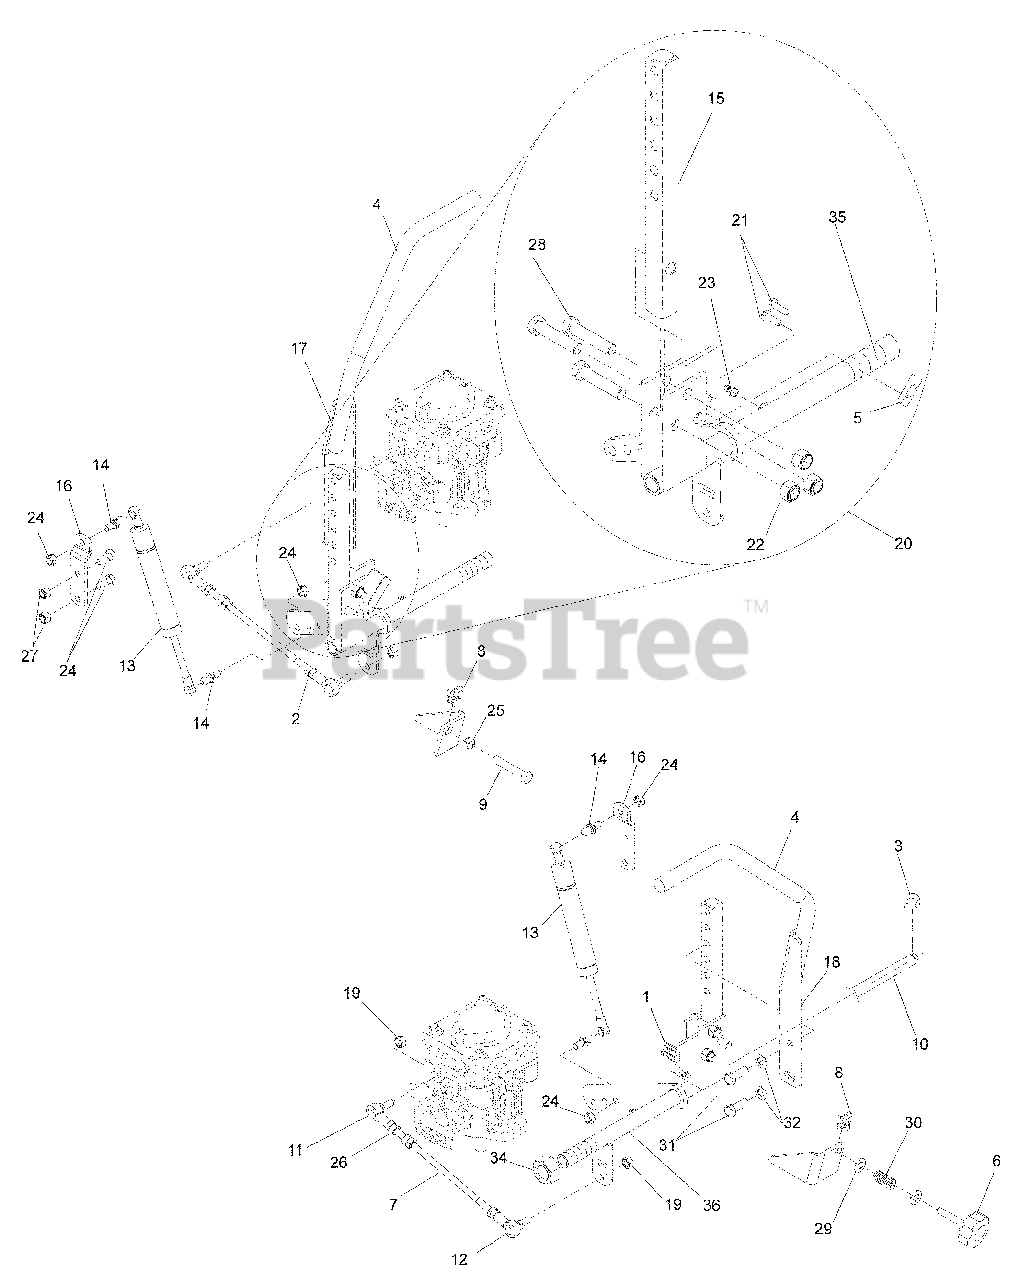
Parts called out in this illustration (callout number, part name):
1	SWITCH, INTERLOCK
2	NUT 5/16-24 HEX HD
5	PLATE, TAPPED
6	KNOB, TRACKING
8	NUT 5/16-18, U-TYPE
9	HCS 5/16-18 x 1¾ TAPBOLT
10	CONTROL SHAFT
11	SPHERICAL ROD END, RT
12	SPHERICAL ROD END, LT
15	ARM, CONTROL SHAFT
16	ARM, DAMPENER
17	DRIVE LEVER, RT w/GRIP
18	DRIVE LEVER, LT w/GRIP
19	NUT 5/16-24 NYLOC
20	DRIVE CONTROL ASSM, RT iZC5221, iZC5223
22	NUT 3/8-16 HEX NYLOC
23	ZERK, STRAIGHT ¼-28
24	NUT 5/16-18 HEX CTRLK
25	NUT 5/16-18 HEX
26	NUT 5/16-24 HEX LH
27	NUT 5/16-18 HEX NYLOC
28	HCS 3/8-16 x 1¾
29	WASHER 5/16 STD FLT
31	HCS 3/8-16 x 1
32	WASHER 3/8 DISK SPRING
33	HCS 5/16-18 x ¾
34	NUT ¾-16 CENTERLOCK
35	DRIVE CONTROL, RT iZC5221, iZC5223
36	DRIVE CONTROL, LT iZC5221, iZC5223
